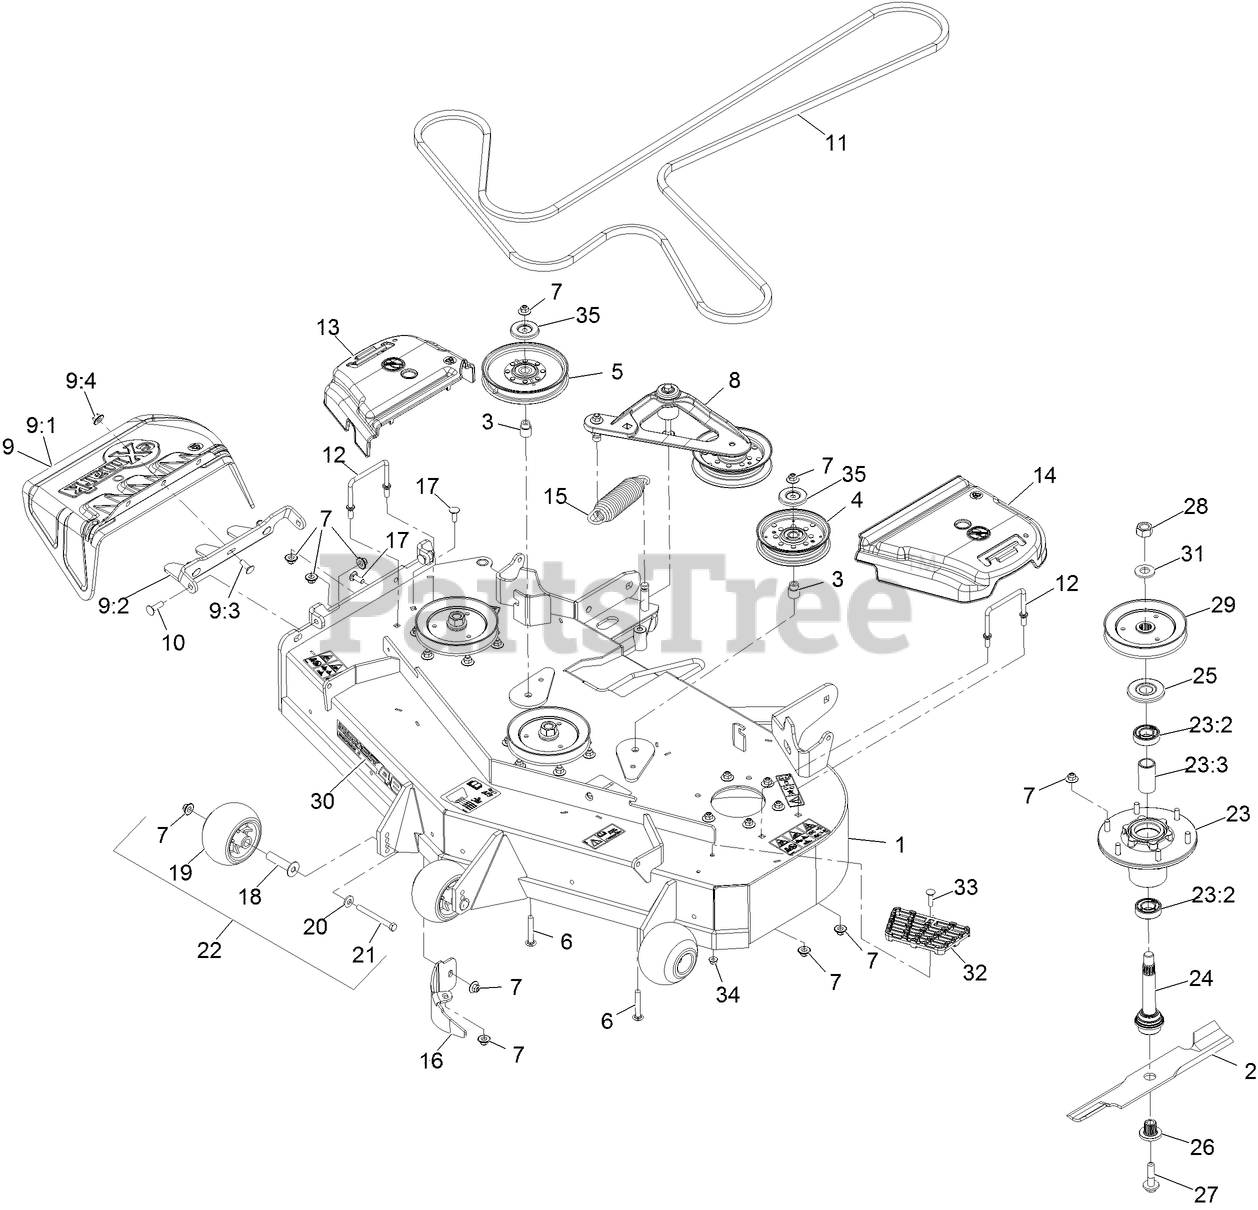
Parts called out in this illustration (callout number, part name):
1	ASM,DECK W/DECALS 48
3	BUSHING-IDLER
4	PULLEY-IDLER, FLAT
5	IDLER-PULLEY
6	SCREW-CARR
7	Nut-Nyloc 3/8-16 Flg
8	DECK IDLER ASM
9	ASM,DISCHARGE CHUTE
9:1	CHUTE,DISCHARGE
9:2	BRACKET,DISCHARGE CHUTE
9:3	SCREW-CARR
9:4	Nut-Nyloc 3/8-16 Flg
10	Bolt-Carriage 3/8-16 X 1 1/4
11	BELT
12	WIREFORM-COVER
13	COVER-BELT, RH
14	COVER-BELT, LH
15	SPRING-EXTENSION
16	BAFFLE-DOGLEG,LZS LZX VT48
17	SCREW-CARR
18	AXLE, ROLLER
19	ROLLER-SCALP, ANTI
20	WASHER-BELLEVILLE
21	SCREW-HH 3/8-16 X 3 3/4 GR 8
22	KIT, ANTI-SCALP ROLLER
23	ASM-CUTTER HSG WITH BEARINGS
23:2	BEARING-BALL
23:3	SPACER-BEARING
24	ASM-SPINDLE AND SEAL
25	GUARD,BEARING TOP .989
26	BUSHING,SPLINED
27	SCREW,SEMS 1/2-20 X 2.19
28	NUT-HEX
29	SHEAVE,BLADE DRIVE 5.90
30	DECAL, 484
32	STEP-DECK
33	Bolt-Carriage 5/16-18 X 1 1/4
34	NUT-HF, NI
35	SHIELD-DUST
